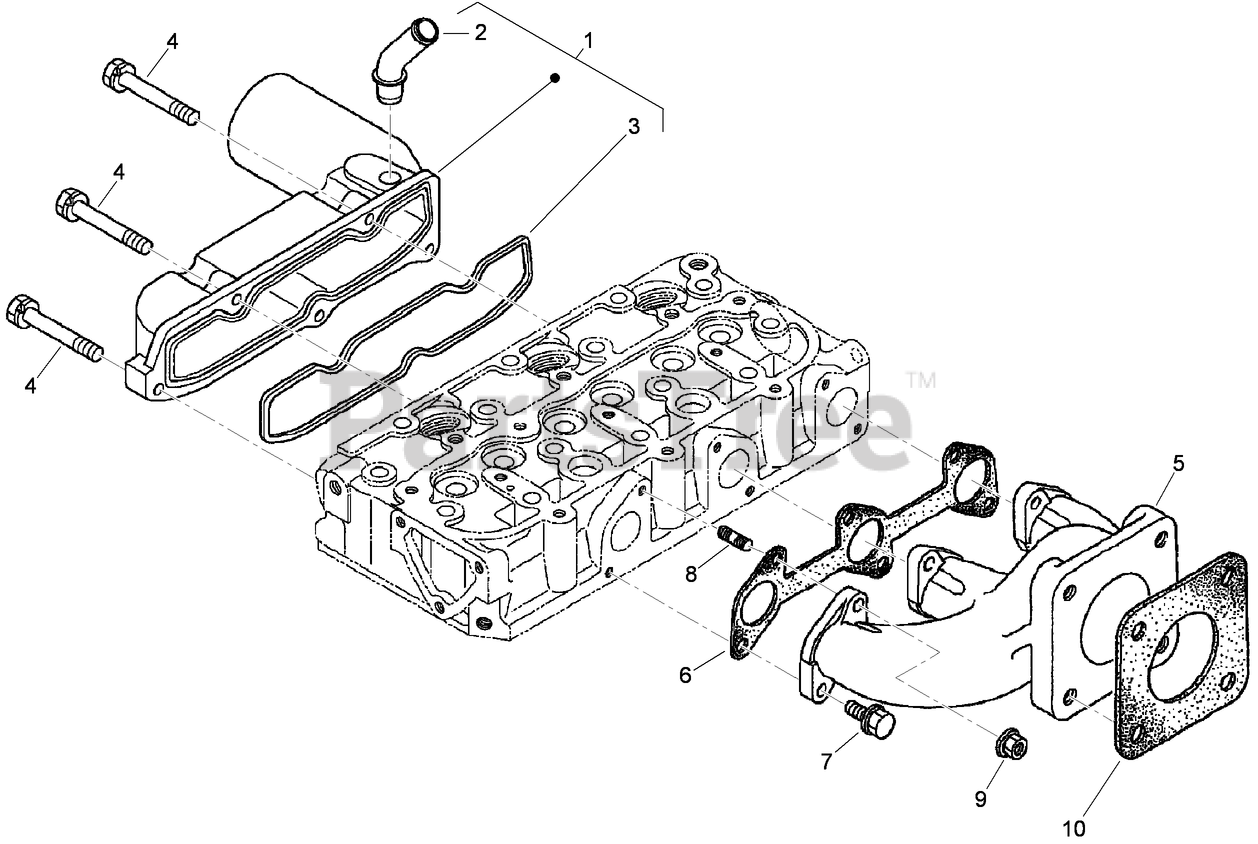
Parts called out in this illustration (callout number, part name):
1	INLET MANIFOLD ASM
2	PIPE-BREATHER
3	GASKET-MANIFOLD, INTAKE
5	MANIFOLD-EXHAUST
6	GASKET-MANIFOLD, EXHAUST
10	GASKET-MUFFLER
